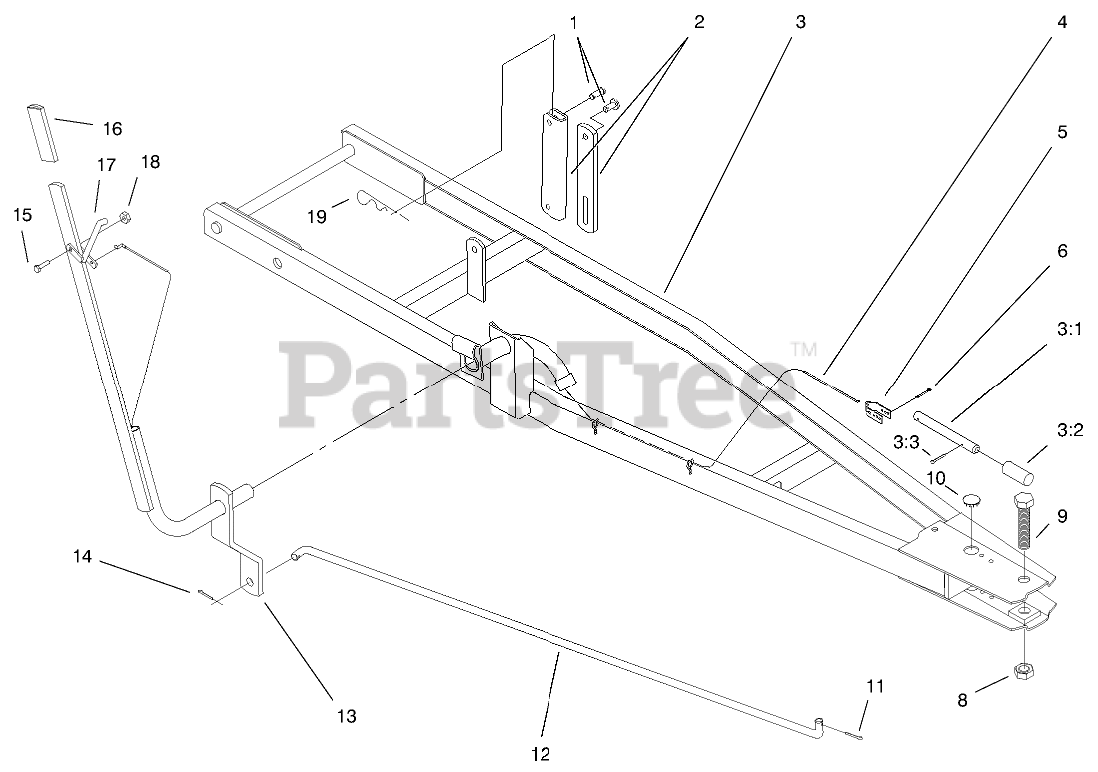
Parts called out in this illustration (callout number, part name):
1	PIN-CLEVIS
1	PIN-WELD
2	LINK - LIFT
3	WA - FRAME PAINT RED
3:1	PIN-INDEX
3:2	SPRING-COMPRESSION
3:3	PIN-COTTER
4	CABLE - INDEXING
5	BRACKET - CABLE END
6	PIN-COTTER
8	NUT-LOCK, NI
9	SCREW-HH
10	PLUG
11	PIN-COTTER
12	ROD - BLADE CONTROL
13	Lever Indexing
14	PIN-HAIR
15	SCREW-HH
16	GRIP
17	LEVER
18	NUT-LOCK
19	PIN-HAIR
